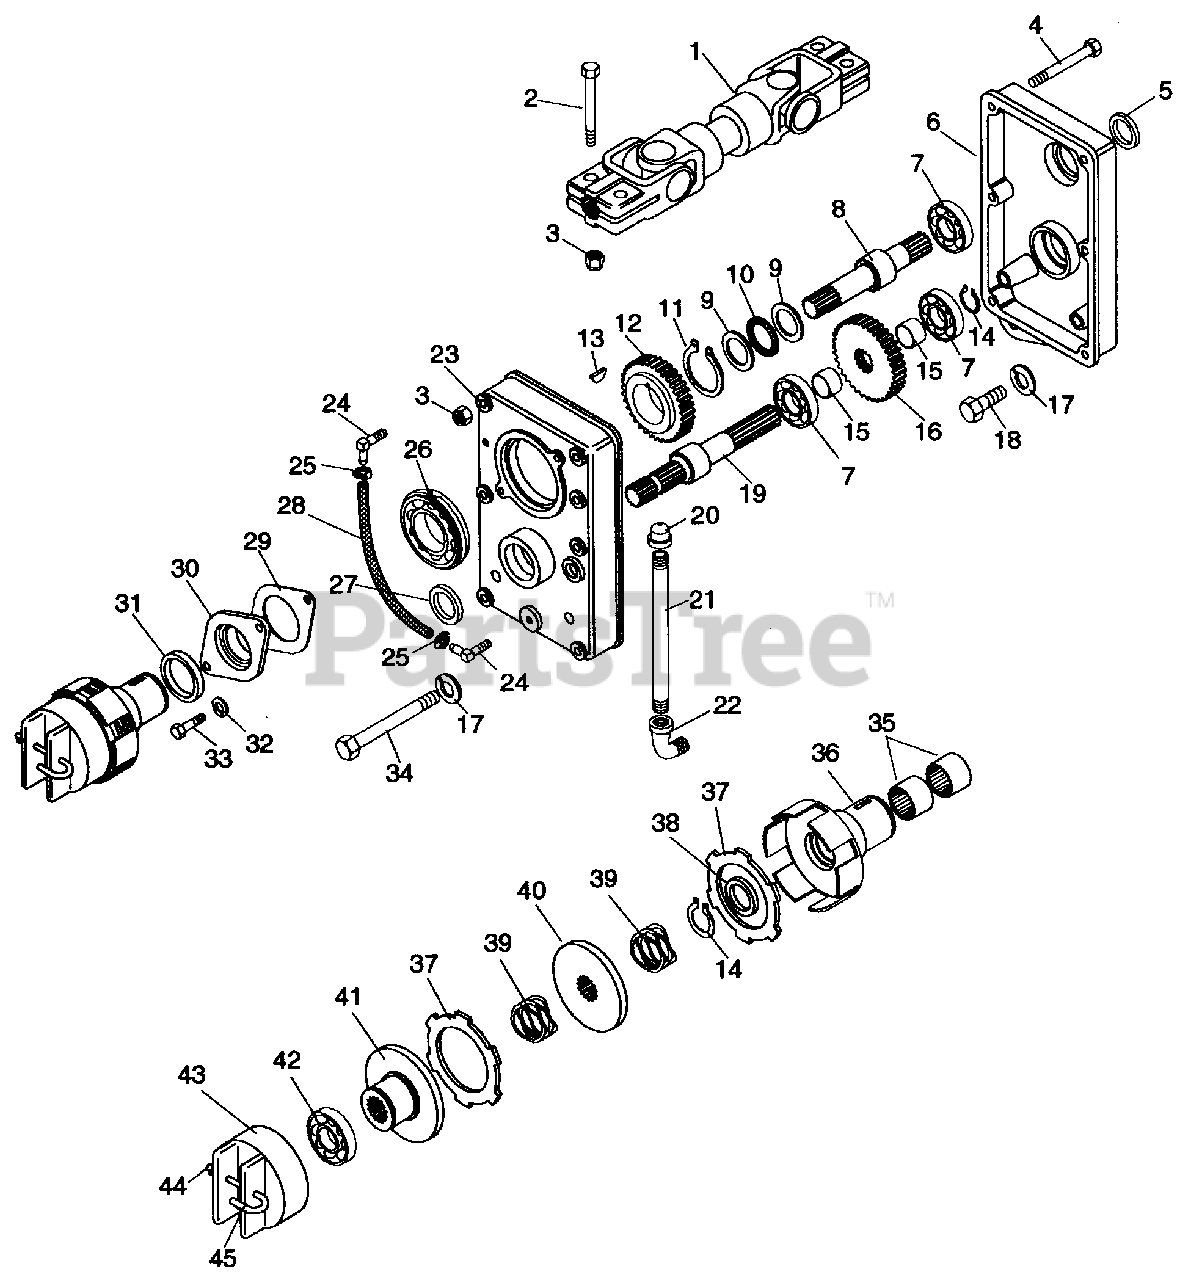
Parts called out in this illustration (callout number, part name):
1	ASM, PTO U-JOINT
2	BLT-HEX .38-16 X 1.75 PL GR 5
3	NUT-LK-NYL .375-16 PL
4	BLT-HEX .38-16 X 3.50 PL GR 5
5	SEAL-LIP .984 X 1.6 X .25
6	CASE, PTO
7	BRG-BALL .984 X 2.047 X .591
8	SHFT, PTO INPUT(UPPER)
9	WSHR-THRST 1.55 X 1.002 X .093
10	BRG-N-THRST 1.0 X 1.55 X .078
11	RG-RTNG-EXT 1.819 X .062
12	GR, PTO INPUT 10DP 41T
13	KEY, WDRF 1/4 X 1 HRD # 15
14	RG-RTNG-EXT .906 X .078
15	BUSH., S1.01 X 1.25 X .645 ST
16	GR, PTO OUTPUT 10DP 45T
17	WSHR-LOCK .50 REG.
18	BLT-HEX .50-13 X 1.50 PL GR 5
19	SHFT, PTO OUTPUT(LOWER)
20	CAP, PIPE 3/8
21	NIPPLE, PIPE .38 X 6.0 UNFIN STL
22	EL .38 X 90 STRT UNFIN MAL IR
23	COVER
24	EL, HOSE
25	HOSE CLAMP
26	BRG BALL 1.97 X 3.14 X .63
27	SEAL-LIP 1.25 X 1.75 X .25
28	HOSE, 1/4 IN VINYL
29	GSKT, FRT PTO CAP
30	CAP, FRONT PTO
31	SEAL 2.250 X 3.002 X .375
32	WSHR-LOCK .313 X .078 PL
33	BLT-HEX .31-18 X .75 PL GR 5
34	BLT-HEX .50-13 X 4.25
35	BRG-ROLLER 1.0 X 1.312 X .75
36	HUB, PTO CLUTCH
37	DISC, CLUTCH
38	SEAL-LIP 1.0 X 1.50 X .25
39	SPRG, WAVE
40	PLT, CLUTCH
41	HUB, CLUTCH ACTUATING
42	BRG-BALL 1.57 X 3.15 X .71
43	TRUNION, FWD-REV CLUTCH
44	PIN-COTR .062 X .75 PL
45	PIN, CLUTCH SPRING
